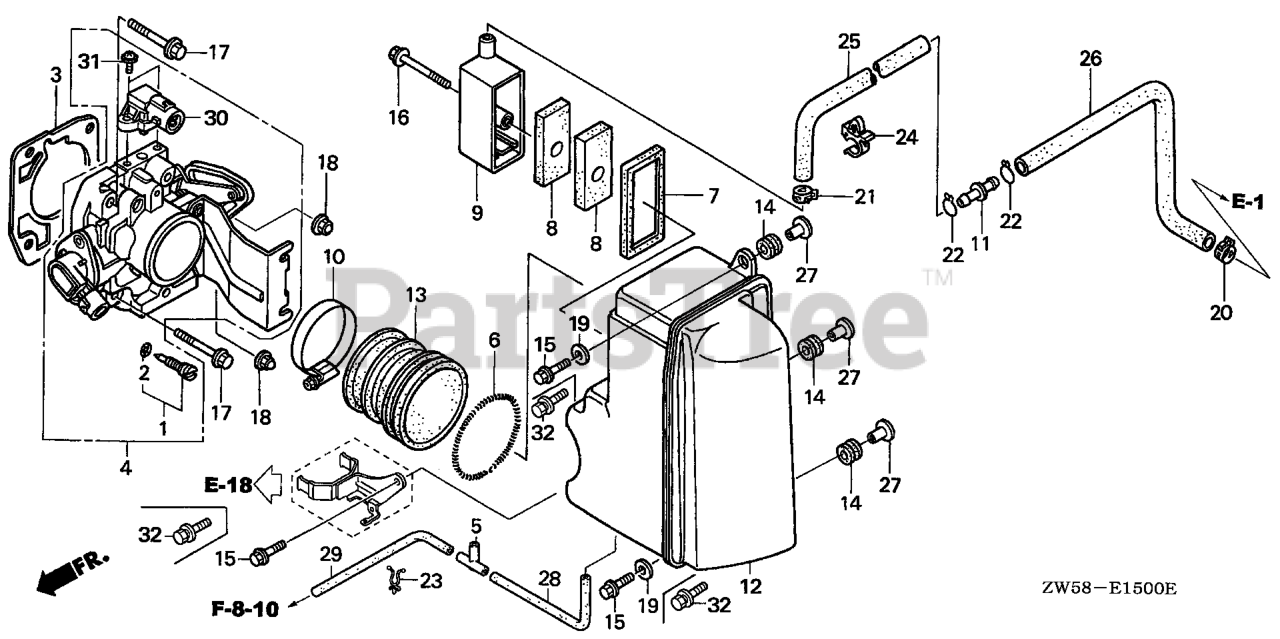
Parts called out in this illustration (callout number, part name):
2	O-RING (9.8X1.9)
3	GASKET, THROTTLE BODY (NIPPON LEAKLESS)
4	BODY ASSY., THROTTLE
5	JOINT A, VACUUM TUBE
6	SPRING, AIR FLOW TUBE
7	GASKET, BREATHER
8	ELEMENT, BREATHER
9	COVER, BREATHER ELEMENT
10	CLAMP, AIR FLOW (70)
11	JOINT, BREATHER TUBE
12	CASE, MUFFLER
13	GROMMET, MUFFLER
14	GROMMET, CASE (LOWER)
15	BOLT, FLANGE (6X25)
16	BOLT, FLANGE (6X50)
17	BOLT, FLANGE (8X40)
18	NUT, FLANGE CAP (8MM)
19	WASHER, PLAIN (6MM)
20	CLAMP, TUBE (D13)
21	CLAMP, TUBE (D15)
22	CLIP, TUBE (B12.5)
23	CLIP, DRAIN TUBE
24	CLIP, CABLE
25	TUBE A, BREATHER
26	TUBE B, BREATHER
27	COLLAR, MODULE IGNITION CONTROL CASE (CDI)
28	BULK HOSE, VINYL (3.5X6.5X8000) (9500(95003-05001-60M) (CARBURETOR NO.)
29	BULK HOSE, VINYL (3.5X6.5X8000) (9500(95003-05001-60M) (CARBURETOR NO.)
30	SENSOR ASSY., MAP
31	SCREW-WASHER (4X16)
